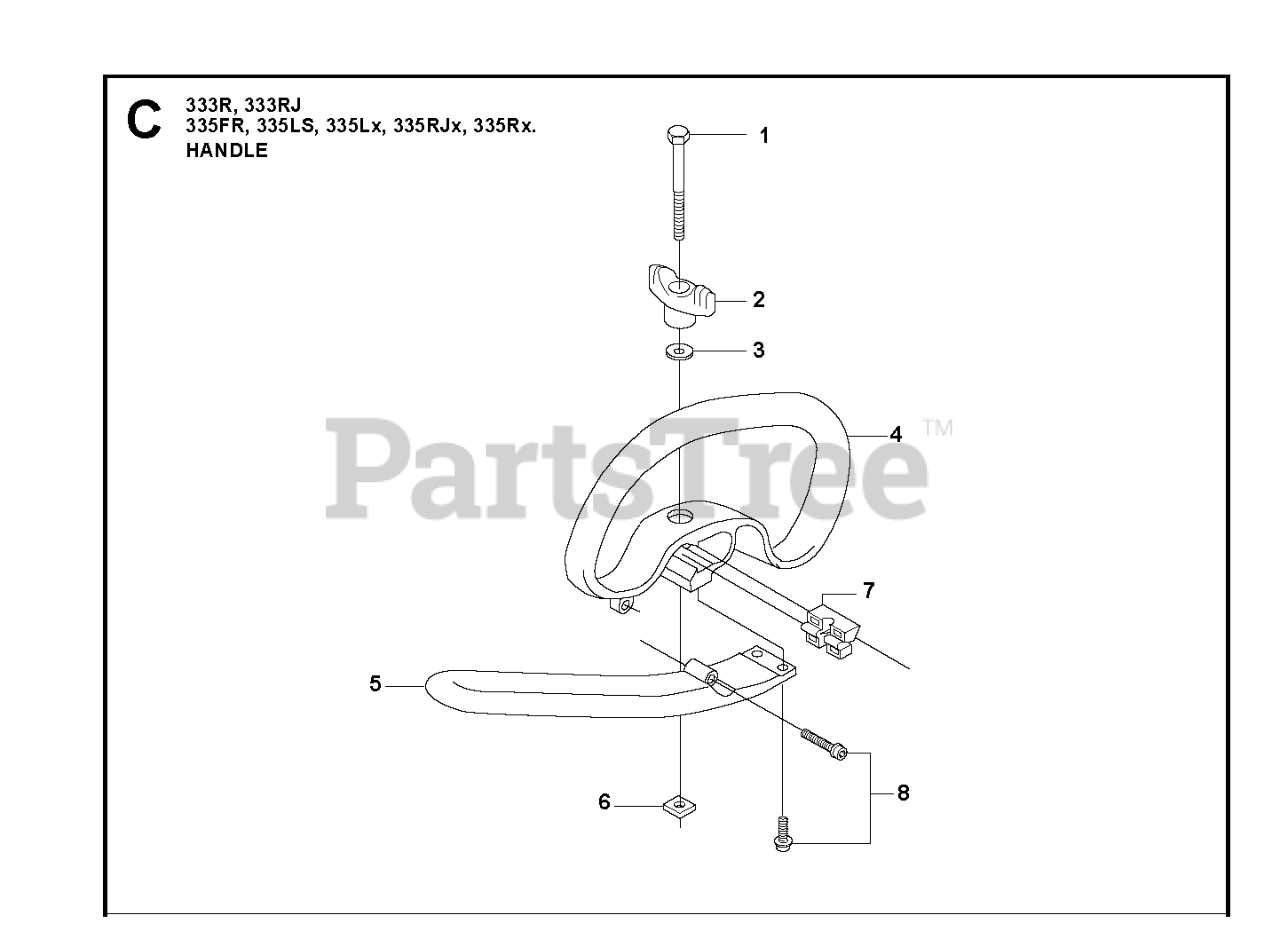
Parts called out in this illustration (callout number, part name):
1	SCREW
1	SCREW M6X50
2	KNOB
3	WASHER
4	RP FRONT HANDLE
5	HANDLE EXTENSION
